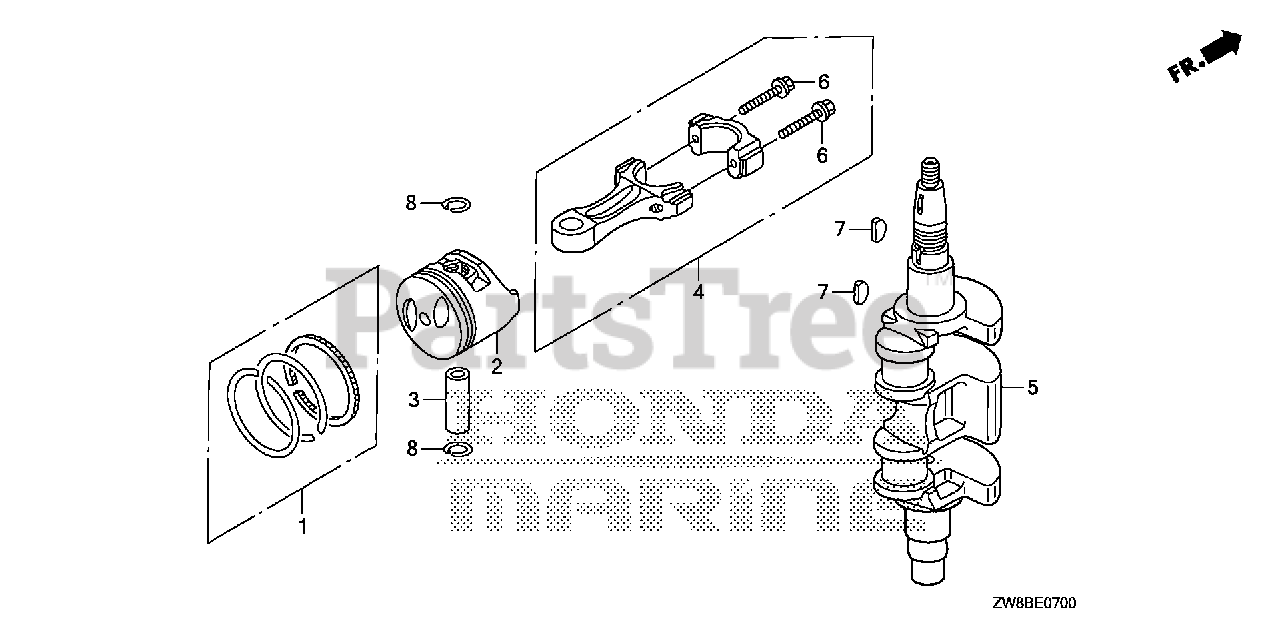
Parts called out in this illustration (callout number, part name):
1	RING SET, PISTON (STD)
3	PIN, PISTON
4	ROD, CONNECTING
5	CRANKSHAFT
6	BOLT, CONNECTING ROD (6X34)
7	KEY, SPECIAL (16X13)
8	CLIP, PISTON PIN (16MM)
